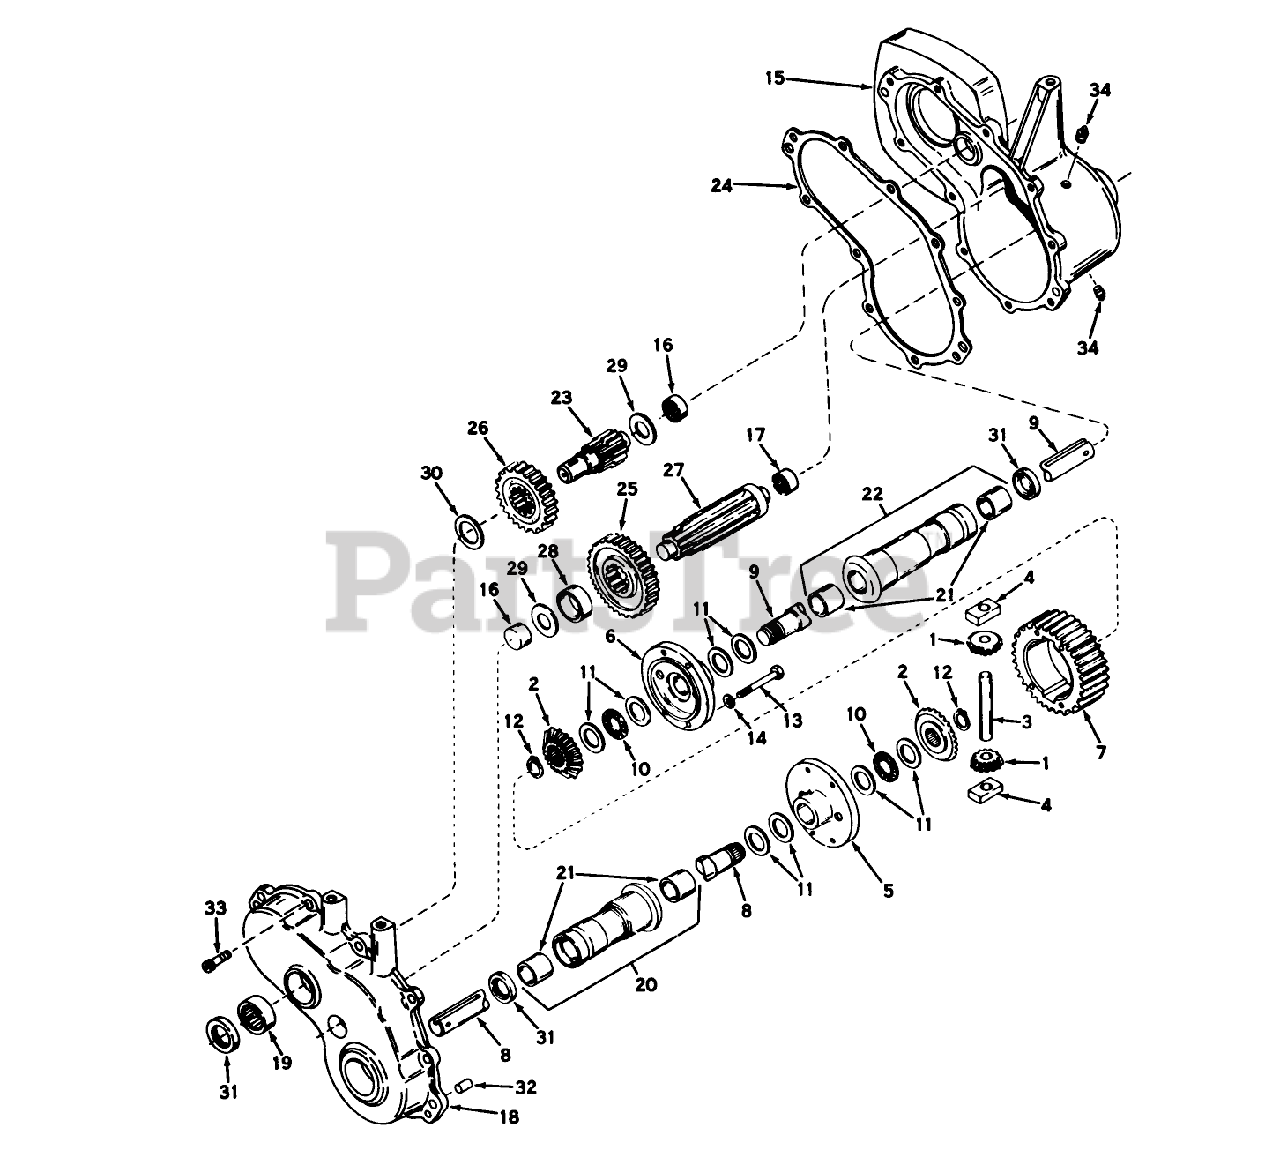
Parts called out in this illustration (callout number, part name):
1	Pinion-Bevel
2	Gear-Bevel
3	Pin-Drive
4	Biock-Drive
5	Carrier, Differential
6	Carrier, Differential
7	Gear, Ring
8	Axle, L.H.
9	Axle, R.H.
10	Bearing-Thrust
11	Washer
12	Ring-Snap
13	Screw-Hex Hd.
14	Lockwasher
15	Case Assy. (Incl. Nos. 16 17)
16	Bearing
17	Bearing-Needle
18	Cover Assy. (Incl. Nos. 16 19)
19	Bearing Needle
20	Housing Bushing Assy., L.H. (Incl. No. 21)
21	Bushing
22	Housing Bushing Assy., R.H. (Incl. No. 21)
23	Shaft, Brake
24	Gasket
25	Gear-Output
26	Gear-Spur
27	Shaft, Output
28	Spacer
29	Washer
30	Washer
31	Seal-Oil
32	Dowel Pin
33	Screw, Hex hd. self tapping
